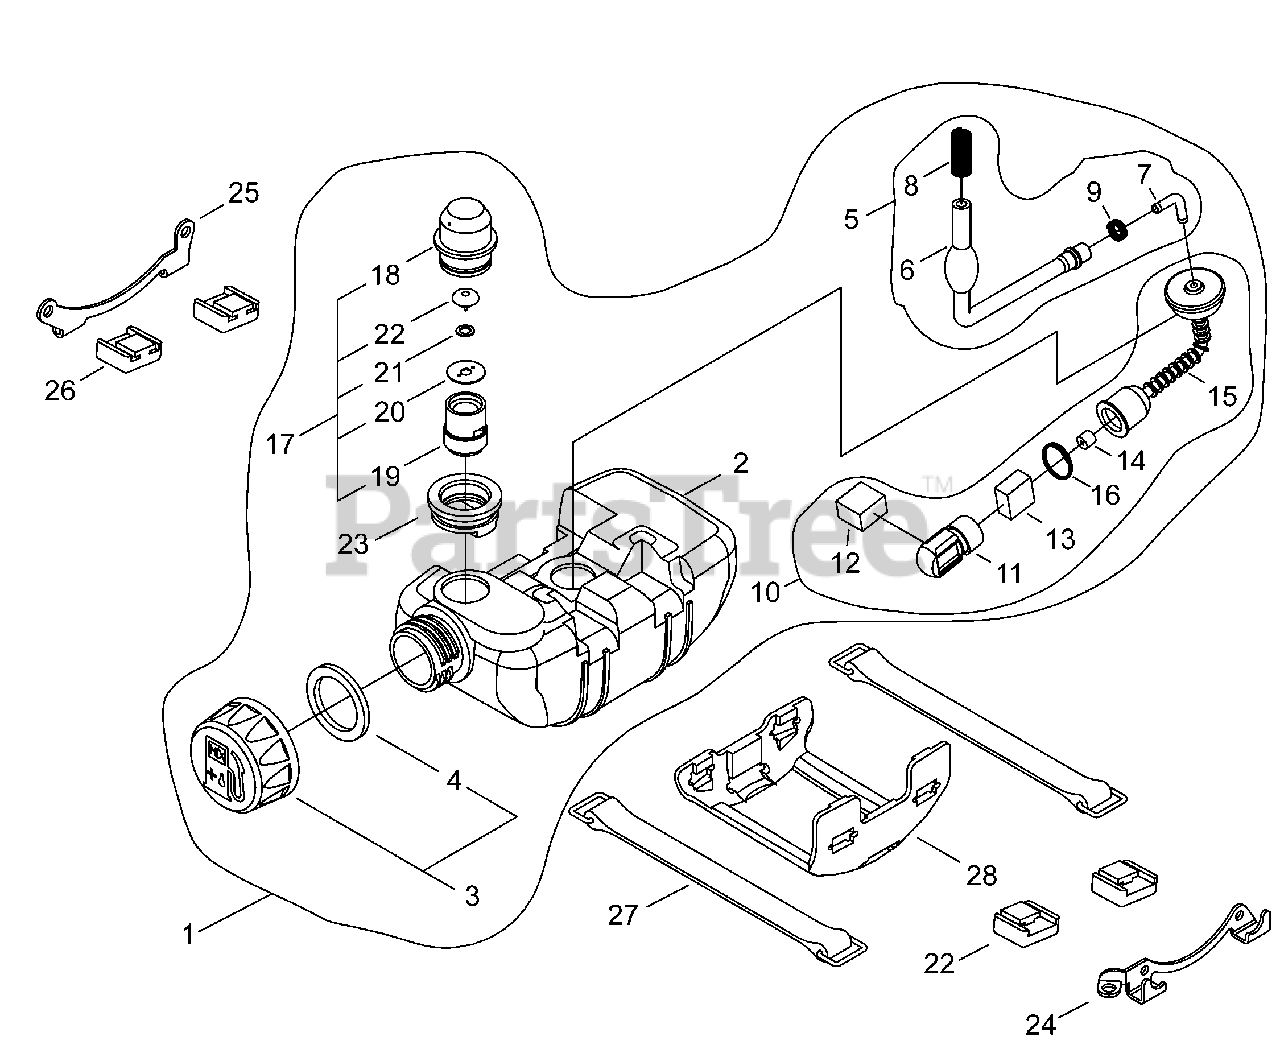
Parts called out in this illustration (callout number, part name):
1	TANK ASSY, FUEL
2	TANK, FUEL
3	CAP ASSY, FUEL
4	GASKET, FUEL CAP
5	PIPE ASSY, FUEL
6	PIPE, FUEL
7	CONNECTOR
8	CLAMP
9	CLIP
10	FILTER ASSY, FUEL
11	WEIGHT
12	FILTER, FUEL - A
13	FILTER, FUEL - B
14	VALVE, CHECK
15	PIPE, FUEL
16	CLIP
17	VENT ASSY
18	CAP, VENT
19	HOLDER, VENT
20	RETAINER
21	WASHER
22	VENT ASSY
23	GROMMET, VENT
24	BRACKET S
25	BRACKET M
26	CUSHION, FUEL TANK
27	STRAP, FUEL TANK
28	GUARD, FUEL TANK
